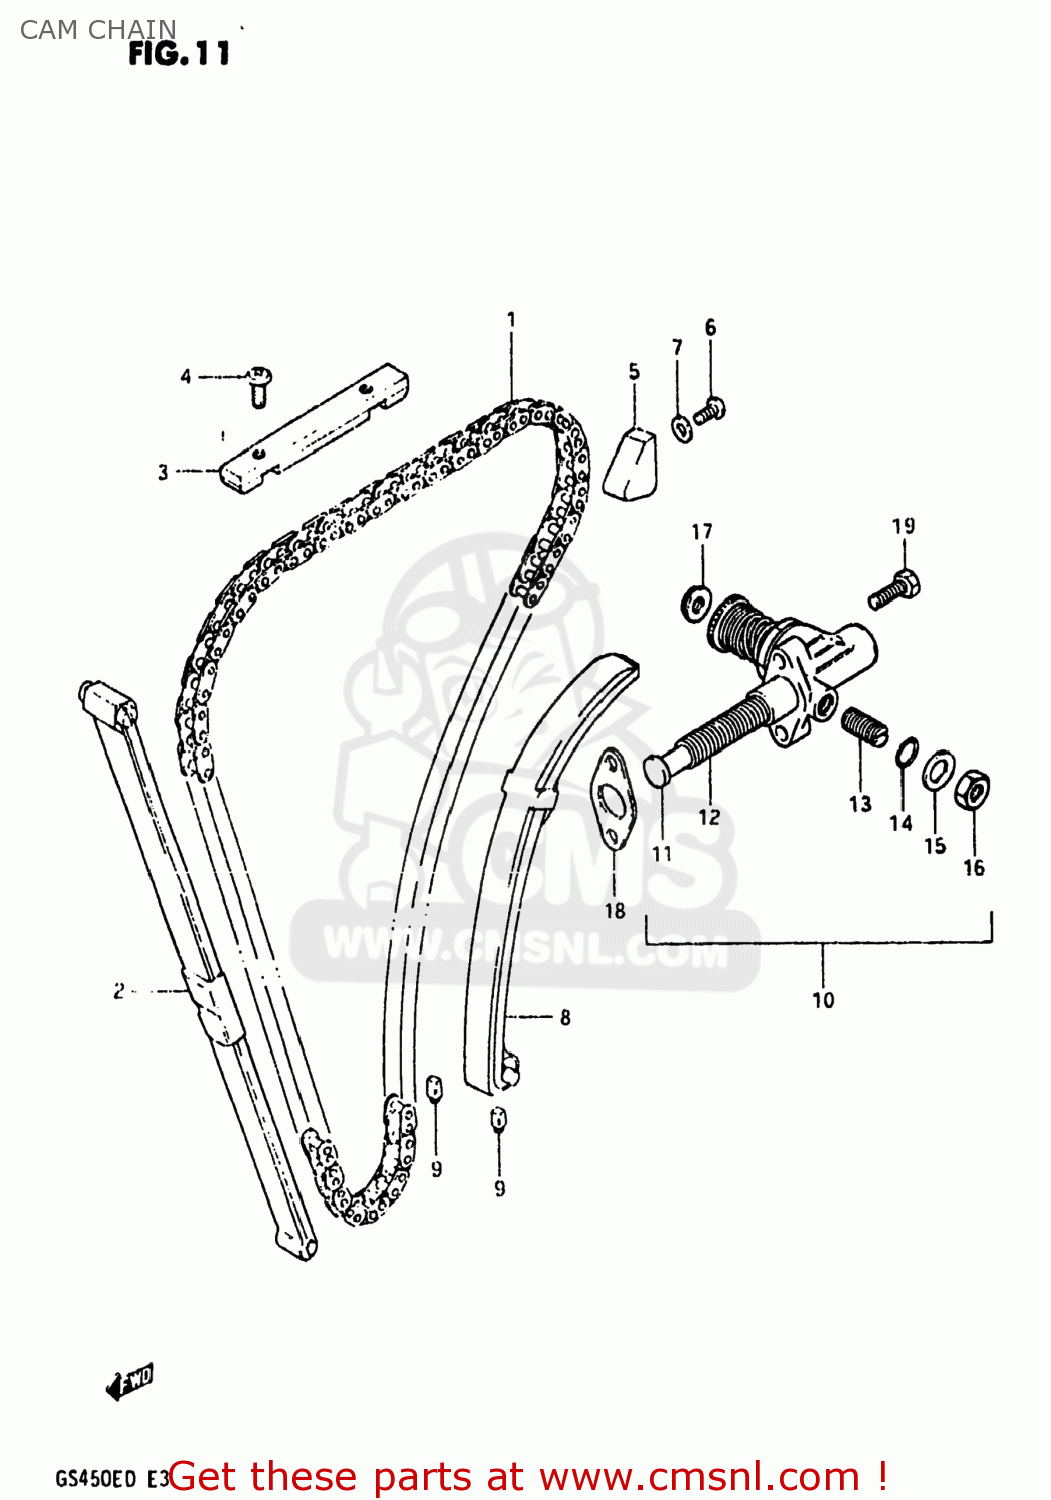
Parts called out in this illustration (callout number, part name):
1	CHAIN,CAMSHAFT DRIVE(120L)
2	GUIDE,CAM CHAIN NO.1
3	GUIDE,CAM CHAIN NO.3
4	SCREW
5	GUIDE,CAM CHAIN
6	BOLT
7	GASKET (NAS)
8	TENSIONER,CAM CHAIN
9	CUSHION,CAM CHAIN TENSIONER
10	ADJUSTER ASSEMBLY,TENSIONER
11	ROD,PUSH
12	SPRING
13	SCREW
14	O-RING
15	WASHER
16	NUT
17	NUT
18	GASKET,TENSIONER ADJUSTER (MCA)
19	SCREW (6X25)
